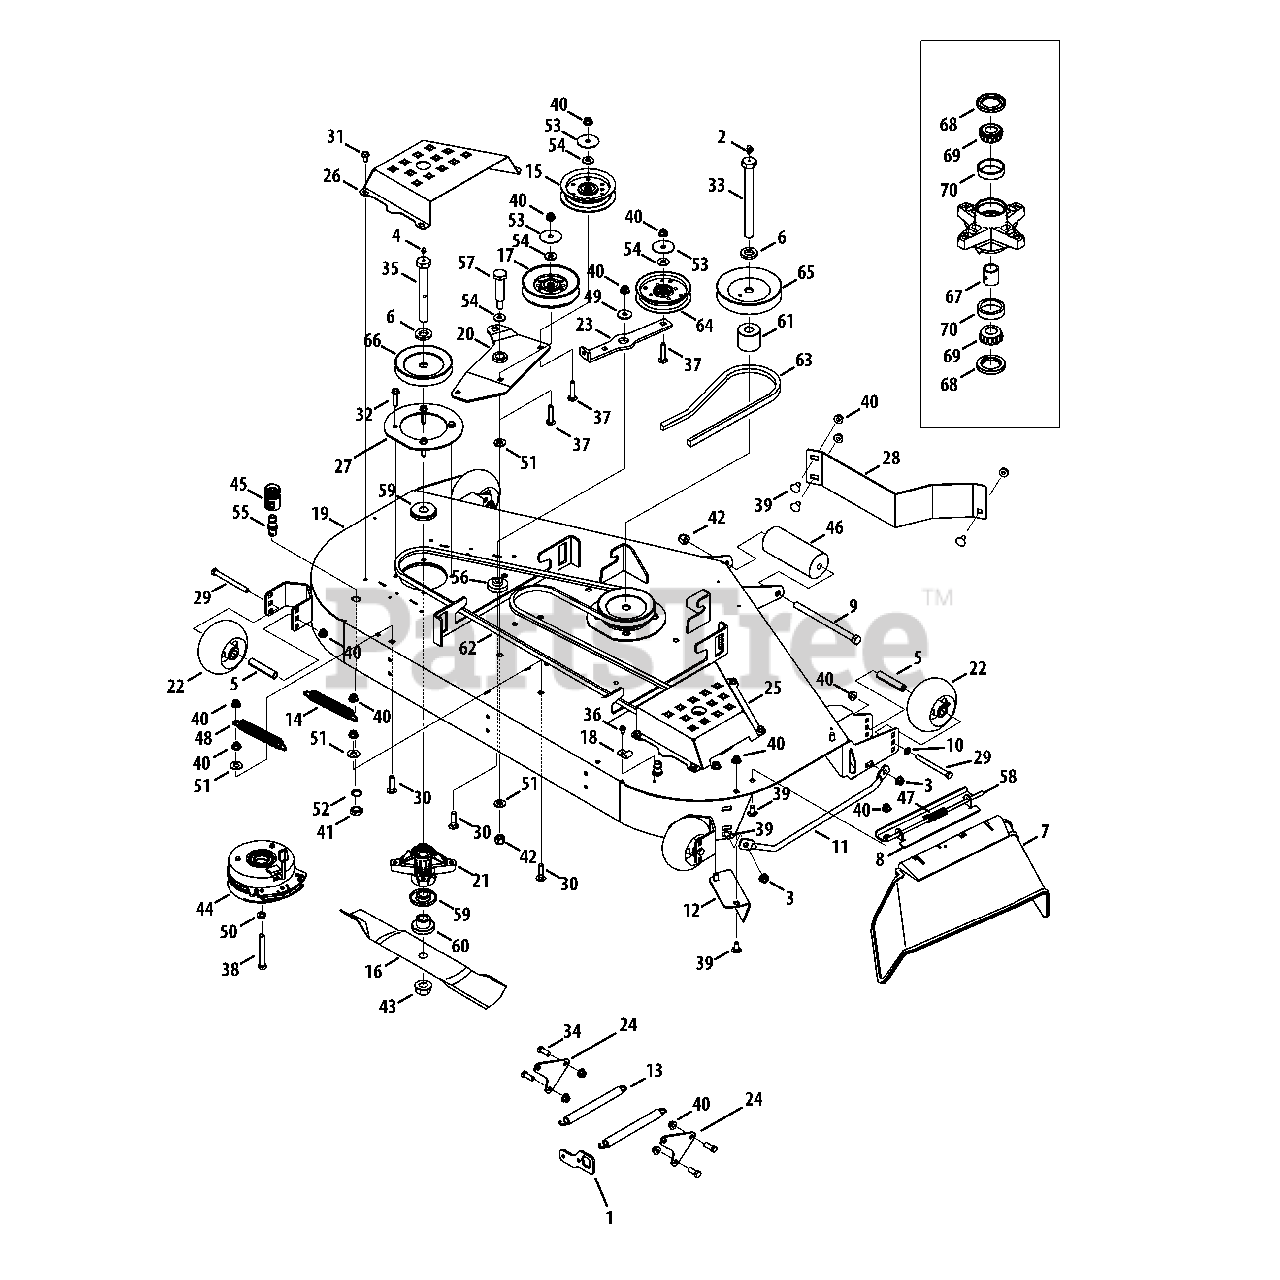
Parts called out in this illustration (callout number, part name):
1	Spring Mount Bracket
2	Grease Fitting, 1/4-28 x .788
3	Counterlock Flange Nut, 3/8-16
4	Straight Grease Fitting, 1/4-28
5	Spacer, .390 x .620 x 3.04
6	Spacer, .812 x 1.47 x .218
7	Fab Deck Deflector Chute
8	Deflector Chute Bracket
9	Hex Screw, 1/2-20 x 7.50
10	Thrust Washer .382 ID x .684 OD
11	Fab Deck Chute Finger Guard
12	Deck Chute Baffle
13	Hook Ext. Spring, .75 x 7.89 x .14
14	Hook Ext. Spring, .94 x 7.57 x .14
15	Idler Pulley, 4.88
16	Hi-Lift Blade, 19.0
17	Idler Pulley
18	Retainer Hook
21	Deck Spindle Assembly
22	Deck Wheel
23	Deck Idler Arm
24	Spring Mount Plate
25	54" RH Belt Cover
26	54" LH Belt Cover
27	Spindle Reinforcement Plate
28	Standard Baffle
29	Hex Screw, 3/8-16 x 4.00
30	Carriage Bolt, 3/8-16 x 1.50
31	Hex Washer Screw, 5/16-18 x .750
32	Flange Hex TT Screw, 5/16-18 x 1.50
33	Hex Screw, 3/4-16 x 8.0
34	Hex Screw, 3/8-16 x 1.00
35	Hex Screw, 3/4-16 x 6.0
36	Hex Washer TT Screw, 1/4-20 x .500
37	Screw, Carriage: 3/8-16 x 1.75"
38	Hex Screw, 7/16-20 x 3.50
39	Carriage Bolt, 3/8-16 x .75
40	Flange Lock Nut, 3/8-16
41	Hex Nut, M16-1.5
42	Nut, Hexlk, 1/2-20, Gr2, Nylon
43	Flange Lock Nut, 3/4-16
44	Electric PTO Clutch
45	Water Nozzle Adapter
46	Front Roller
47	Torsion Spring
48	Extension Spring, .91 x 7.33
49	Washer, .411 x 1.25 x 1.00
50	Lock Washer, 7/16
51	Flat Washer, .390 x 1.500 x .134
52	Lock Washer, 17 x 23.8 x 1.95
53	Flat Washer, .406 x 1.92 x .060
54	Washer, .406 x 1.00 x .105
55	Water Deck Nozzle
56	Shoulder Spacer, .854 x .280
57	Shoulder Bolt, 3/8-16 x .74 x 2.47
58	Chute Deflector Rod
59	Deck Spindle Spacer
60	Spindle Spacer, .76 x 2.0 x 1.1
61	Spacer, .760 x 2.00 x 1.69
62	V-Belt
64	Idler Pulley, 4.25
65	V-Type Pulley
66	V-Type Pulley
67	Bearing Spacer
69	Cone Bearing, .750"
70	Bearing Cup, .750"
